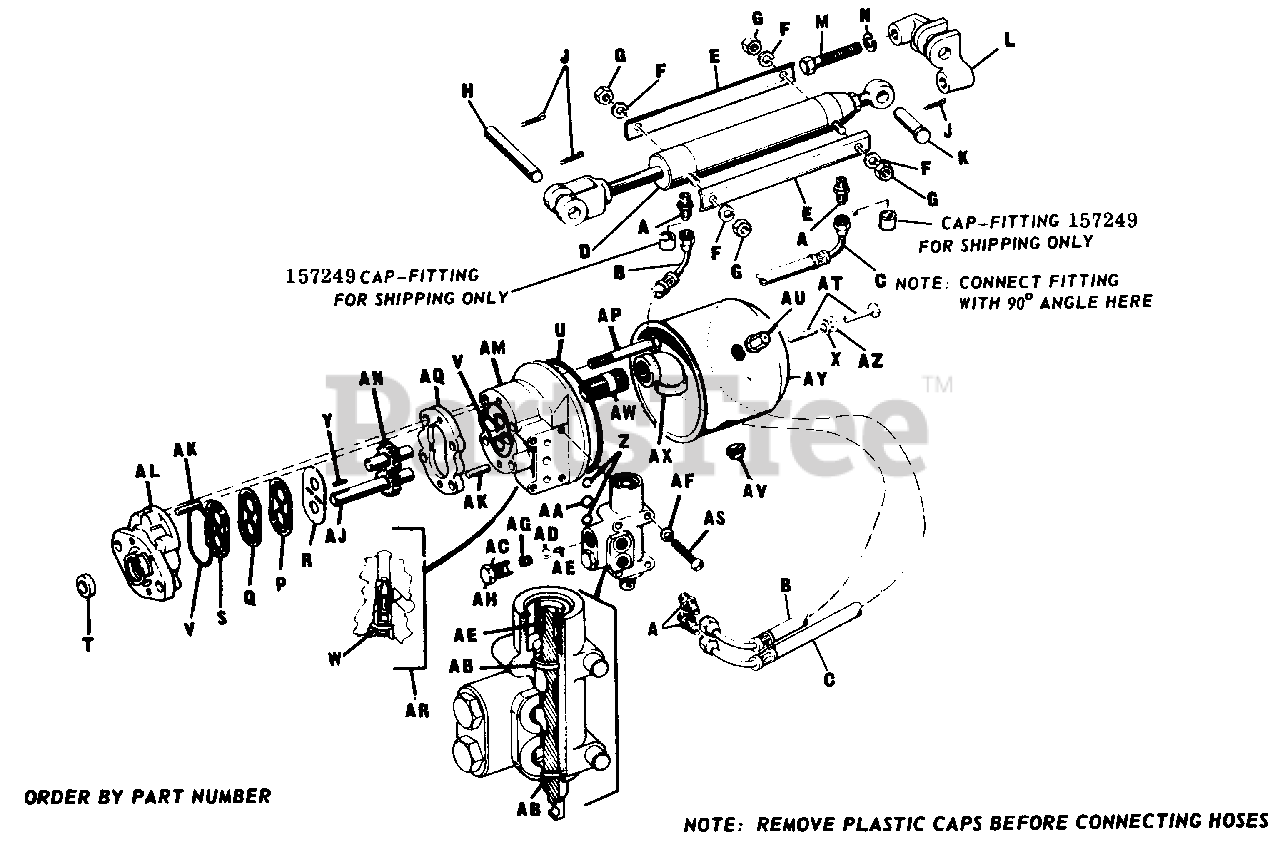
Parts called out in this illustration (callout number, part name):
B	Hose Assembly
C	Hose Assembly
D	Cylinder Assembly
F	Lock Washer, 5/16"
G	Full Hex. Nut, 5/16"-18
J	Cotter Pin, 1/8" x 3/4"
K	Ram Bracket Pin
L	Ram Bracket
M	Hex. Cap Screw 7/16"-14 x 2-1/4"
N	Lock Washer, 7/16"
P	Heat Shield (for service only)
R	Wear Plate
T	Rotary Seal
X	Stat-O-Seal
Y	Shaft Drive Key
AF	Lock Washer 1/4"
AJ	Drive Gear Assembly
AK	Dowel Pin
AL	Front Cover Assembly
AM	Back Cover Assembly
AN	Driven Gear Assembly
AQ	Center, Section Machined
AR	Relief Valve Assembly
AU	Filler Cap Plug
AV	Drain Plug
AW	Inlet Nipple
AX	Inlet Elbow
AY	Tank Assembly
AZ	Flat Washer, 1/4"
